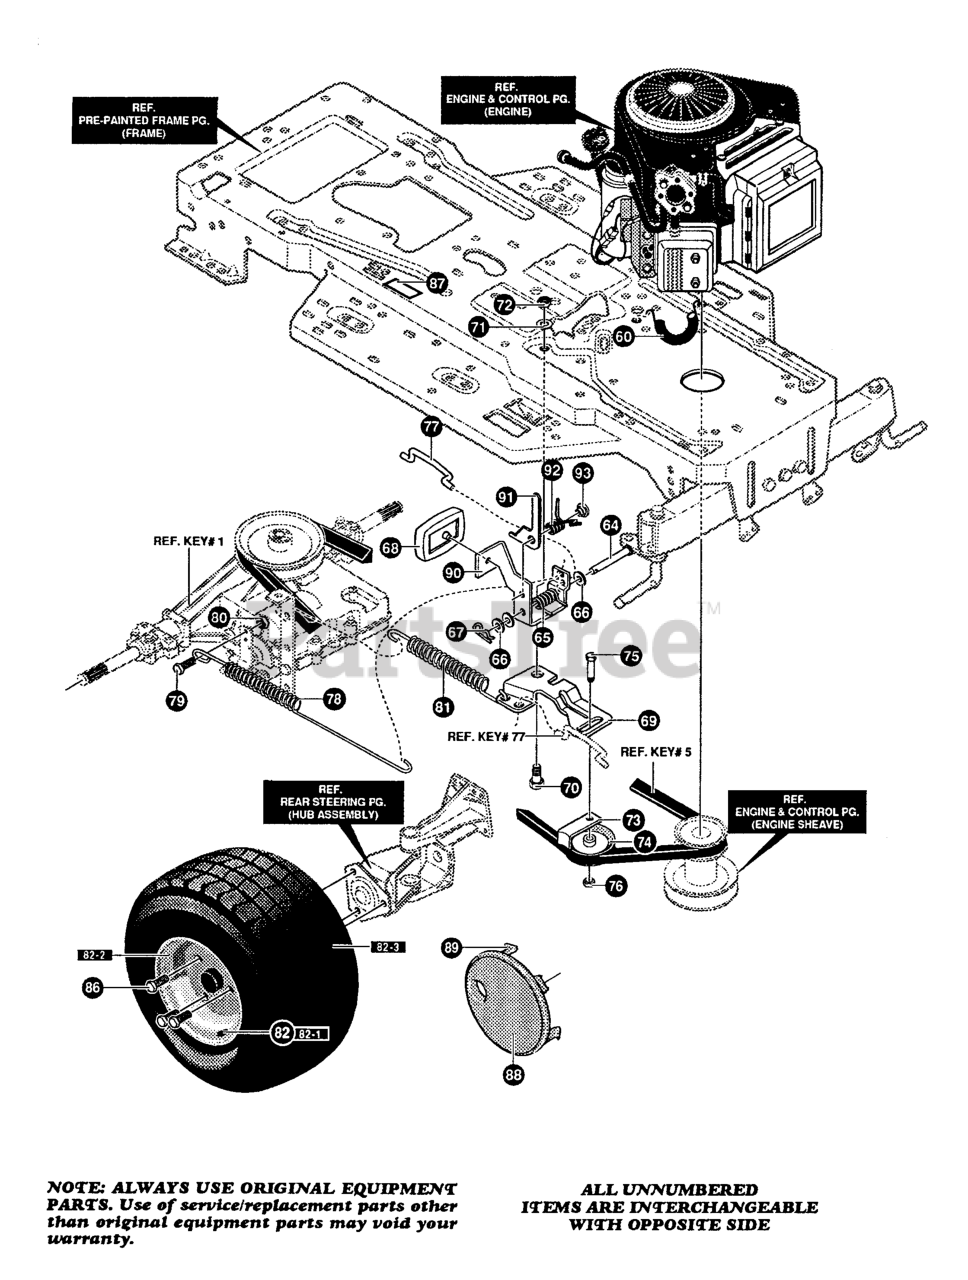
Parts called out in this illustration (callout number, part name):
60	SPRING, DRAG LINK
64	PIN, CLEVIS
65	SPRING, BRAKE PEDAL
66	WASHER, FLAT .504 x .75 x .059
67	PIN, HAIR
68	PAD, CLUTCH BRAKE
69	ARM, IDLER TRACTION
70	BOLT, .625 x .135
71	WASHER, FLAT .333 x .87 x .119
72	NUT, 5/16-18
73	RETAINER, BELT
74	PULLEY, IDLER
75	BOLT, 3/8-16 x 1.50
76	NUT, 3/8-16
77	ROD, CLUTCH 3.92"
78	SPRING, BRAKE
79	BOLT, .495 x .31
80	NUT, 5/16-18
81	SPRING, CLUTCH
82	TIRE & RIM ASSEMBLY, 20"
82-1	VALVE STEM
82-2	RIM, WHEEL
82-3	TIRE, 20"
86	SCREW, 1/2-20 x .50
87	DECAL, 4WS PATENT
88	HUB CAP, 8"
89	CLIP, HUBCAP TINN
90	PEDAL CL/BRAKE
91	LEVER, PARK BRAKE
92	SPRING, PARKING BRAKE
93	RIVET, SHSET
